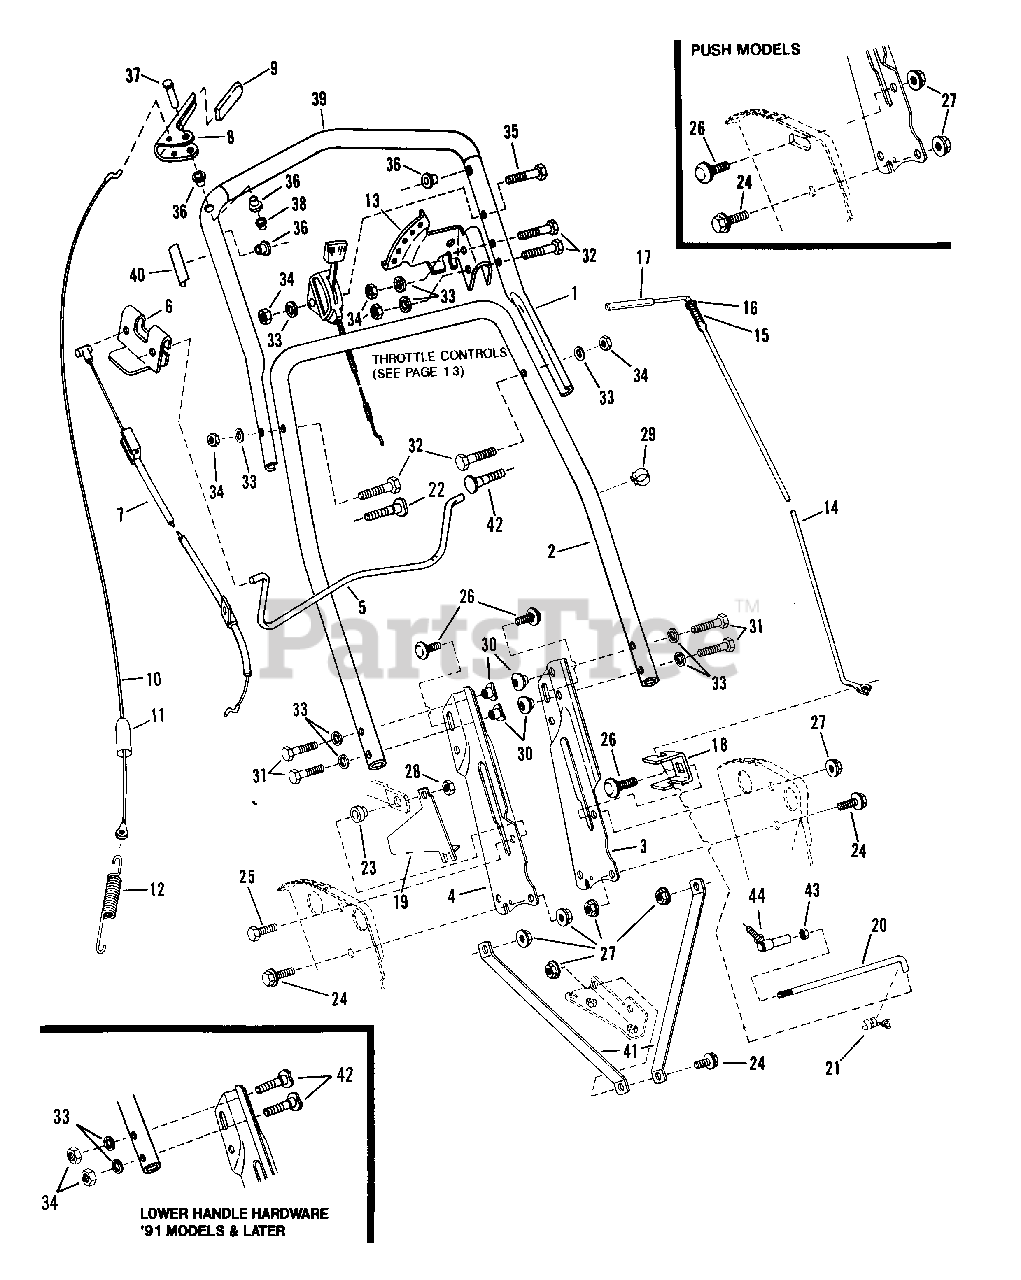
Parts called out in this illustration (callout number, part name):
1	HANDLE, Upper
2	HANDLE, Middle
3	HANDLE, Lower Left Hand
4	HANDLE, Lower Right Hand
5	BAIL, OPC Control (12.2" Wide)
6	CLIP, Blade Control
7	CABLE, Blade Control
8	HANDLE, Wheel Drive
9	GRIP, Wheel Drive Handle
10	CABLE, Clutch Pull (Z-BEND)
11	COVER, Vinyl
12	SPRING, Clutch
13	SECTOR, Speed
14	LEVER, Speed Control
15	SPRING, Speed Control
16	WASHER, 3/8" Flat
17	GRIP, Speed Control Handle
18	ANCHOR, Speed Control
19	GUIDE, Lower V-Belt
20	LINK, Transfer
21	CLIP, Transfer Rod
22	BOLT, 5/16-18 x 2 Curved Head
23	BUSHING, Differential
24	BOLT, 5/16-18 x 3/4 Flange Lock
25	CAPSCREW, 5/18-24 x 1
26	BOLT, 5/16-18 x 5/8 Carriage
27	NUT, 5/16-18 Hex Flange Lock
28	NUT, 5/16-24 Center Lock
29	CLIP Cable/Wiring
30	NUT, 5/16-18 Curved Head
31	SCREW, 5/16-18 x 2" Hex Cap
32	CAPSCREW, 1/4-28 x 1-3/8
33	LOCKWASHER, 1/4 Internal Tooth
33	LOCKWASHER, Internal Tooth
34	NUT, 1/4-20 Hex
34	NUT, 5/16-18 Hex
35	CAPSCREW, 1/4-28 x 1-3/4
36	BUSHING
37	PIN, Clutch Handle
38	PUSH-NUT (for handle pin)
39	GRIP, Foam 18"
39	GRIP, Foam 13.5"
40	DECAL, Blade Control
41	STRAP, Handle
42	BOLT, 5/16-18 x 1-1/2" Curved Head
43	NUT, 1/4-28 Hex
44	JOINT, Ball
